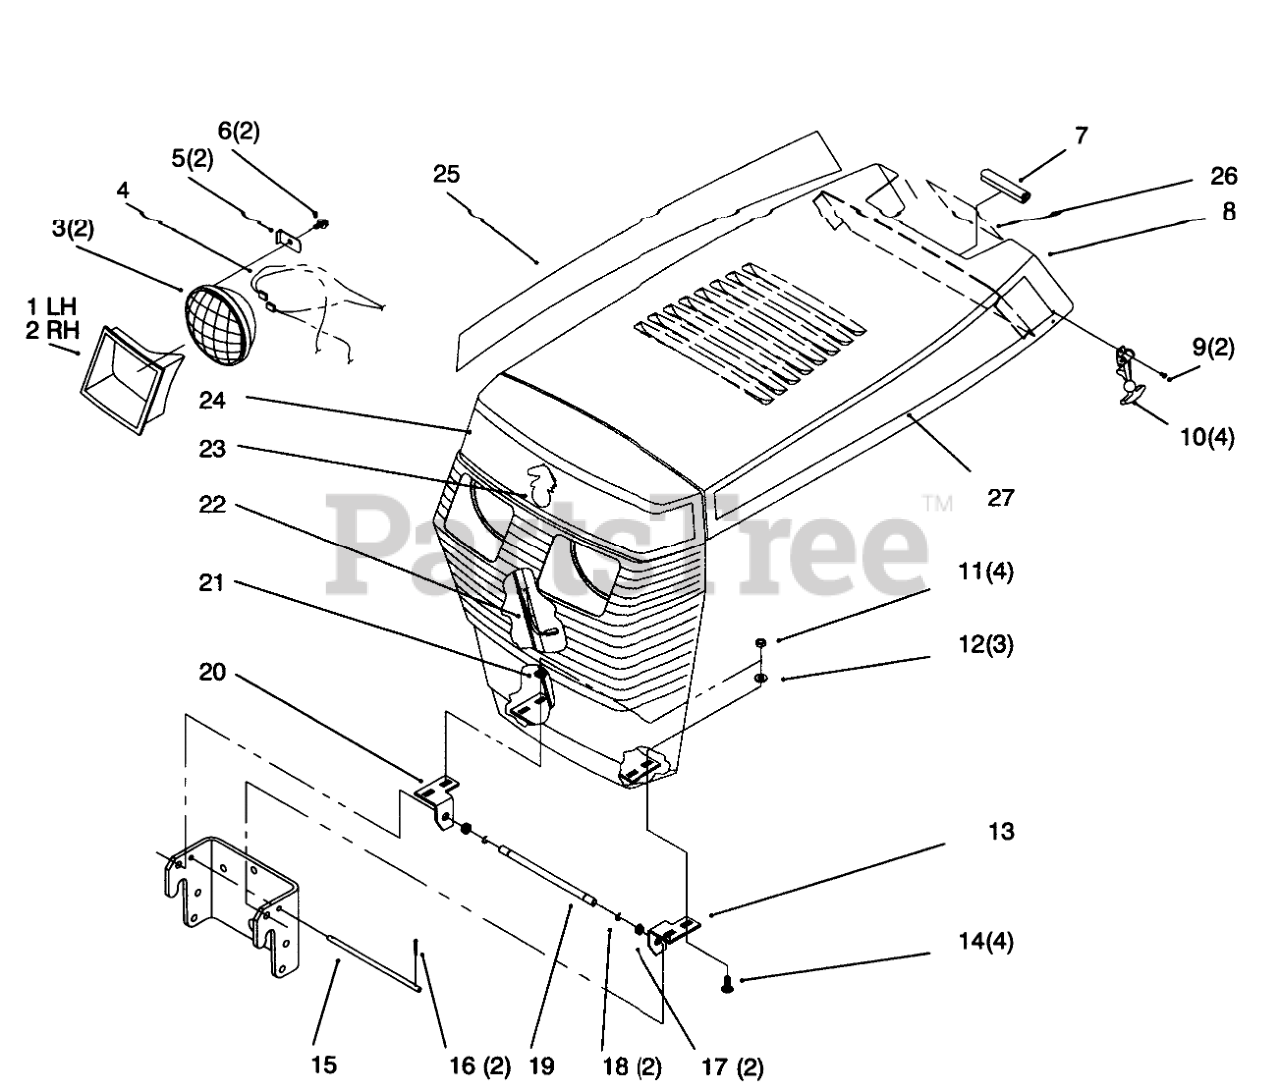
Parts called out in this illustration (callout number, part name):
1	BEZEL-HEADLIGHT, LH
2	BEZEL-HEADLIGHT, RH
3	HEADLAMP
4	LIGHT GROUND WIRE
5	LOCK-HEADLIGHT
6	SCREW-HWH
7	EDGING-CONSOLE
8	Hood
9	RIVET-POP
10	HANDLE ASM
11	NUT-LOCK, NI
12	WASHER-FLAT
13	BRACKET-GRILL, LH
14	SCREW-CARR
15	ROD-HOOD STOP
16	PIN-COTTER
17	BUSHING-NYLINER
18	RING-RETAINING
19	ROD-GRILL PIVOT
20	BRACKET-GRILL, R H
21	WASHER-LOCK, INTERNAL
23	LOGO (GOLD)
24	DECAL-FRONT HOOD, TOP
25	DECAL - RH HOOD TOP
26	DECAL - DANGER
27	DECAL - LH HOOD TOP
